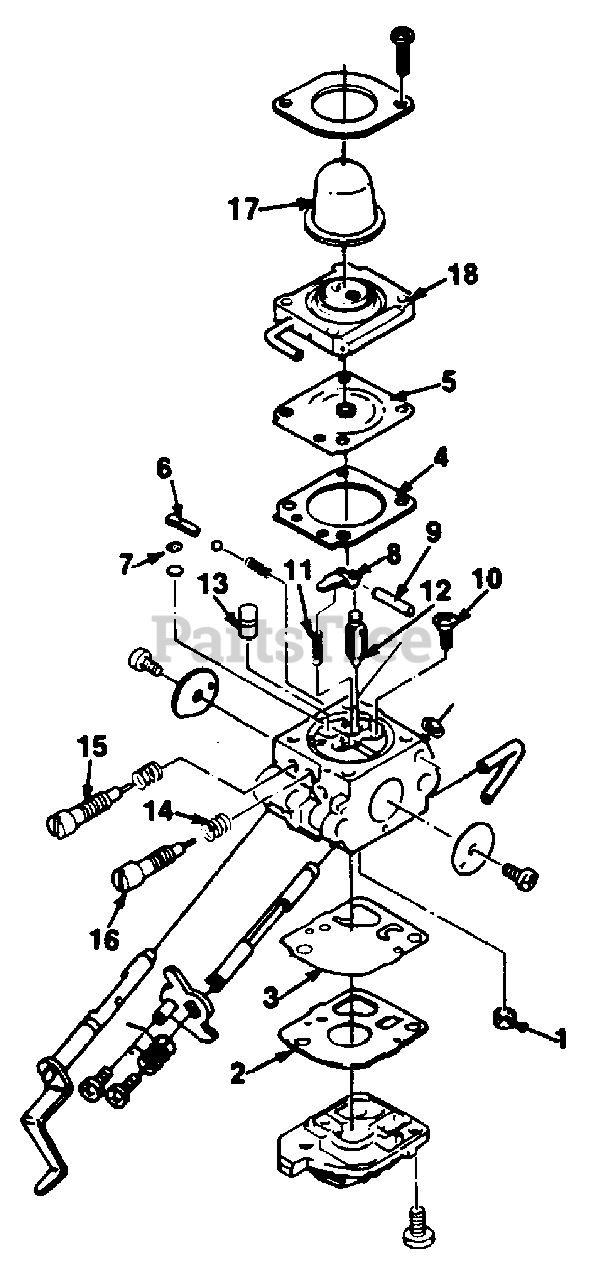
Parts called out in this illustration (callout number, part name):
1	REPAIR KIT
2	REPAIR KIT
3	REPAIR KIT
4	REPAIR KIT
5	REPAIR KIT
6	REPAIR KIT
7	REPAIR KIT
8	REPAIR KIT
9	REPAIR KIT
10	REPAIR KIT
11	REPAIR KIT
12	REPAIR KIT
13	REPAIR KIT
14	REPAIR KIT
15	REPAIR KIT
16	REPAIR KIT
17	PRIMER BULB KIT
18	PRIMER BASE KIT
